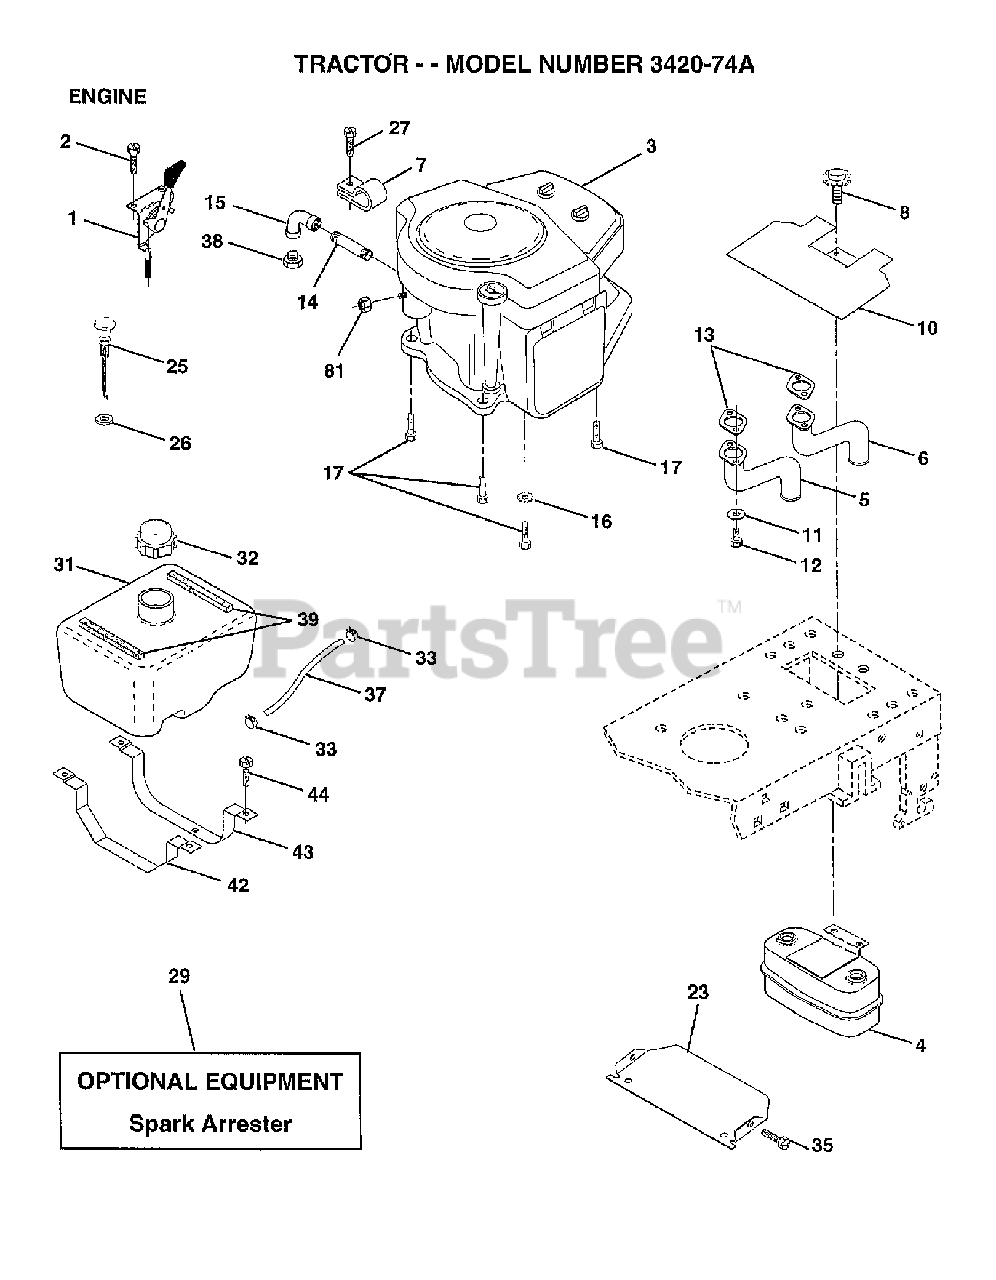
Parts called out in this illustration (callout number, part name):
1	DECK W/DECALS 72" HUS
3	Poulan TBD
4	MUFFLER.TWIN.CYL.LOW.TONE
5	EXHAUST ASM. LEFT
6	EXHAUST ASM. RIGHT
10	SHIELD HEAT LT
11	LOCKWASHER
13	GASKET (B&S 692282)
14	NIPPLE, PIPE 3/8NPT X 4-1/2
15	ELBOW
16	LOCKWASHER
25	CONTROL.CHOKE.51.00.BLK.W/BEND
26	NUT KEPS 3/8 - 24 UNF
27	SCREW.TT.#10-32X.5.3/8.FLANGE
29	KIT.SPARK ARRESTOR(392390 B&S)
33	HOSE CLAMP
35	Screw, Lt
37	LINE FUEL 7.5"
